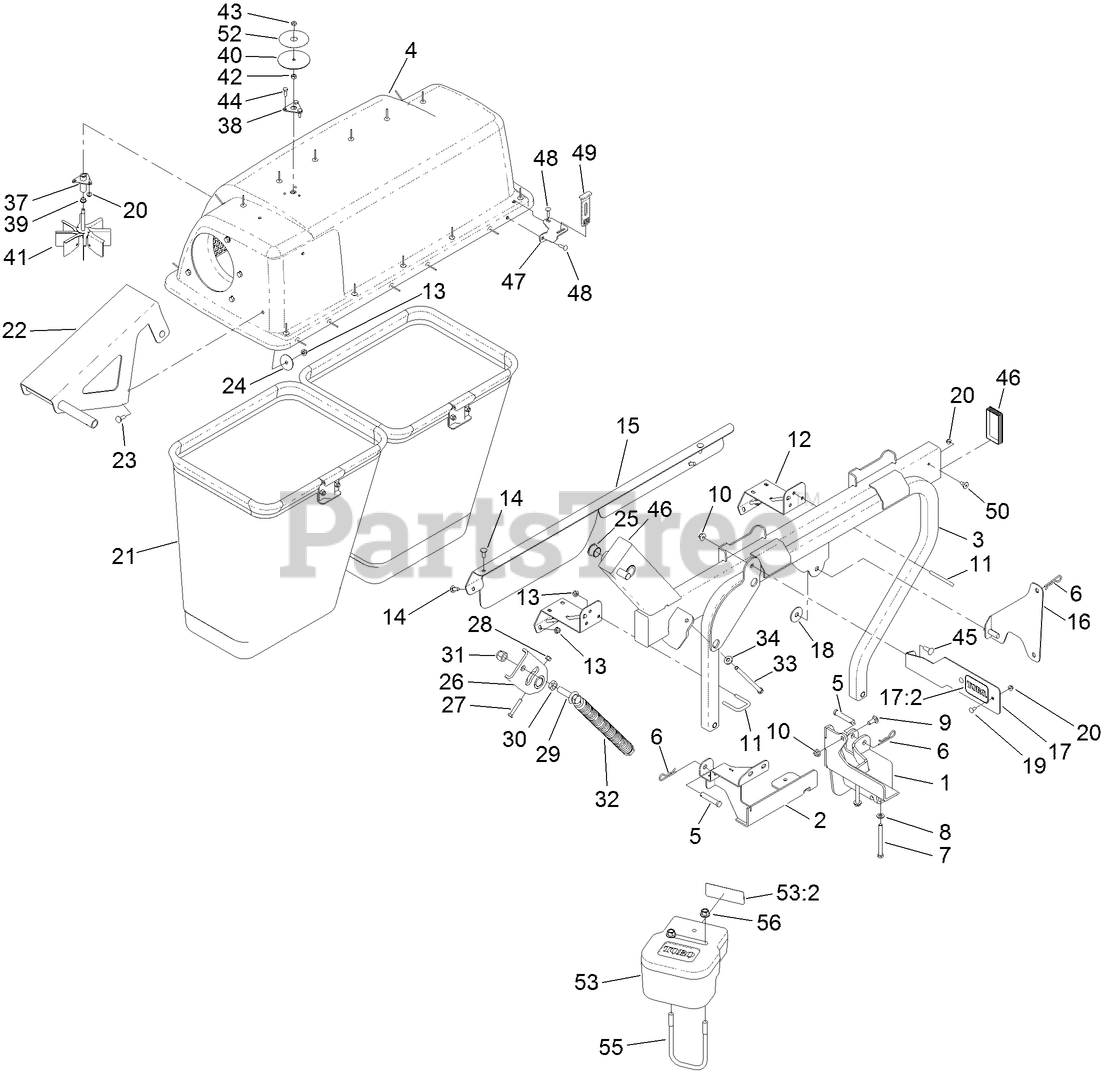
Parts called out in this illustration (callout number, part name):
1	MOUNT-BAGGER
2	BRACKET-EXTENSION, TUBE
3	FRAME-BAGGER
4	HOOD ASM
5	PIN-CLEVIS
6	PIN-COTTER
7	SCREW-HH
8	WASHER-FLAT
9	BOLT-CARR
10	NUT-HF, NI
11	U-BOLT-SQUARE
12	COVER, WHEEL
13	NUT-HF, NI
14	BOLT-CARR
15	COVER-WHEEL
16	MOUNT-SUPPORT, BAGGER
17	BRACKET-MOUNT, BAGGER W/DECAL
17:2	DECAL
18	WASHER-THRUST
19	SCREW-CARR
20	NUT-HF
21	BAG AND FRAME ASM
22	PIVOT-HOOD
23	BOLT-CARR
24	WASHER
25	BUSHING
26	BELLCRANK ASM
27	SCREW-HH
28	NUT-LOCK, NI
29	SCREW-HH
30	NUT-JAM
31	NUT-LOCK, NI
32	SPRING-EXTENSION
33	BOLT-TAP, HH
34	WASHER-BELLEVILLE
37	MOUNT-FILL INDICATOR
38	PLATE-FILL INDICATOR
39	BUSHING-FLANGED
40	PLATE-FILL INDICATOR
41	BAG FILL FAN ASM
42	NUT-HEX, SIDE DEFORM
43	NUT-JAM
44	SCREW-HH
45	SCREW-CARR
46	CAP-END
47	BRACKET-STRAP
48	SCREW-CARR
49	STRAP-HOLD DOWN
52	DECAL-ROTATION INDICATOR
53	WEIGHT ASM
53:2	DECAL-WARNING, COUNTERWEIGHT
55	U-BOLT
56	NUT-LOCK
